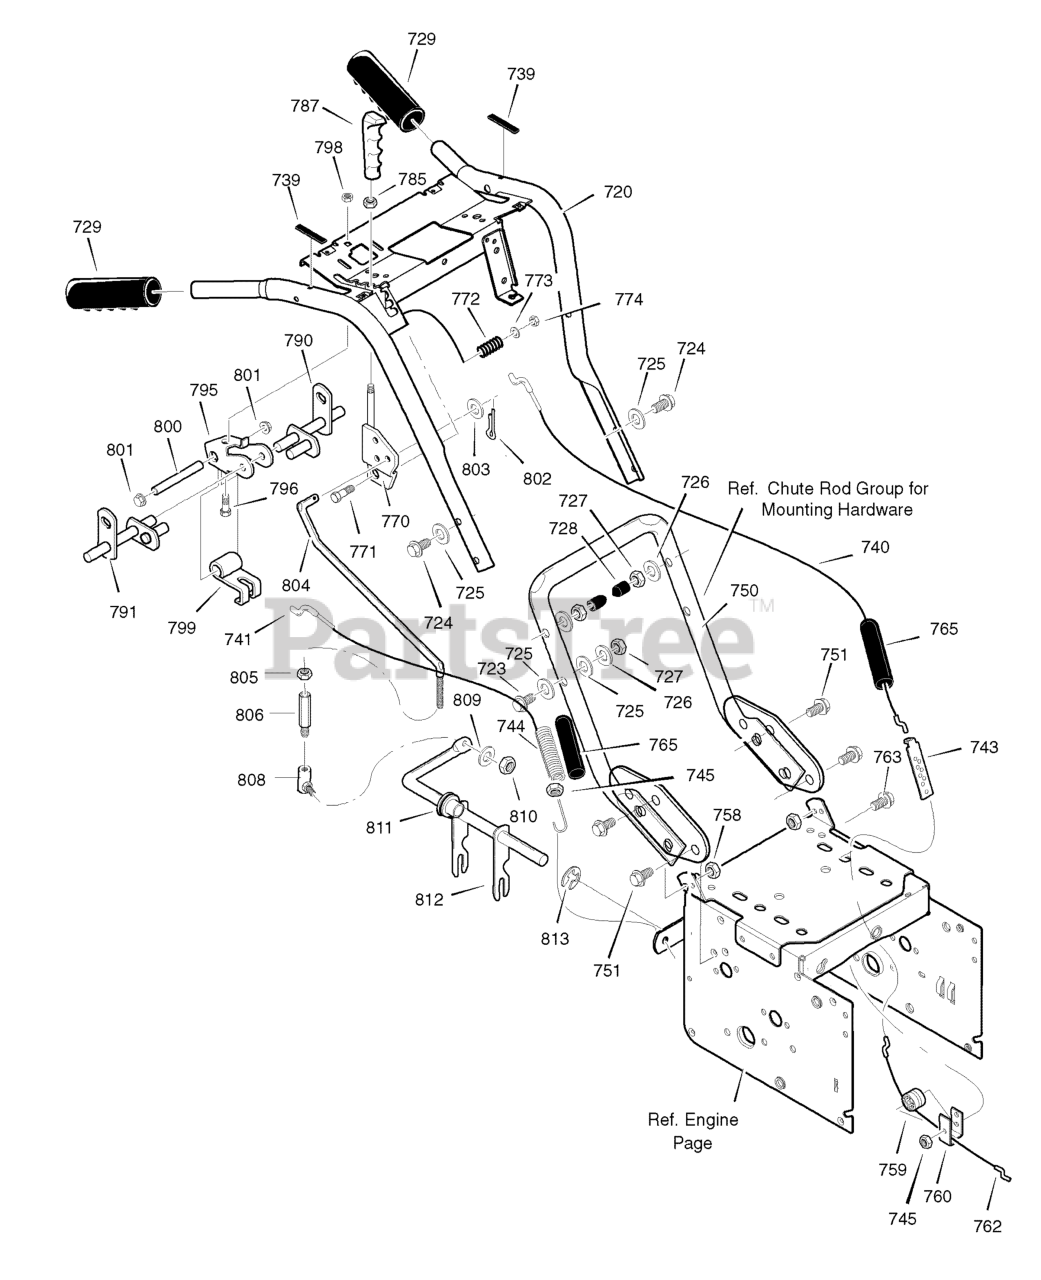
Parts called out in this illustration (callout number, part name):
720	HANDLE ASSEMBLY
723	SCREW, 3/8-16 X 2.00
724	SCREW
725	WASHER, Flat, 13/32
726	WASHER
727	NUT
728	STOP, PLASTIC
729	GRIP, HANDLE
739	BUMPER
740	CABLE, AUGER CLUTCH
741	CABLE, DRIVE
743	BRACKET, CABLE ADJUST
744	SPRING, CLUTCH
745	NUT, HEX
750	HANDLE, LOWER
751	SCREW
758	NUT 5/16-18 REGHEX
759	SPOOL, CABLE
760	BRACKET, SPOOL
762	CABLE, LOWER DRIVE
763	BOLT, HEX 1/4-20 X 1.5
765	BOOT, CABLE
770	BRACKET, SHIFT
771	SCREW
773	WASHER, Flat, 13/32
774	NUT, HEX
785	NUT, HEX
787	KNOB, SHIFT
790	ROD, ASSEMBLY LH
791	ROD, ASSEMBLY RH
795	BRACKET, CAM
796	SCREW
798	NUT, NYLOCK
799	CAM LOCK
800	PIN, SPRING PIVOT
801	NUT, PUSH ON
802	PIN, COTTER
803	FLATWASHER
804	ROD, SPEED CONTROL
805	NUT, 5/16-18
806	ADAPTER, ROD
808	BALLJOINT, STEEL
809	WASHER
810	NUT, 5/16-18
811	BEARING, FLANGE
812	ROD, YOKE
813	RETAINER, RING
